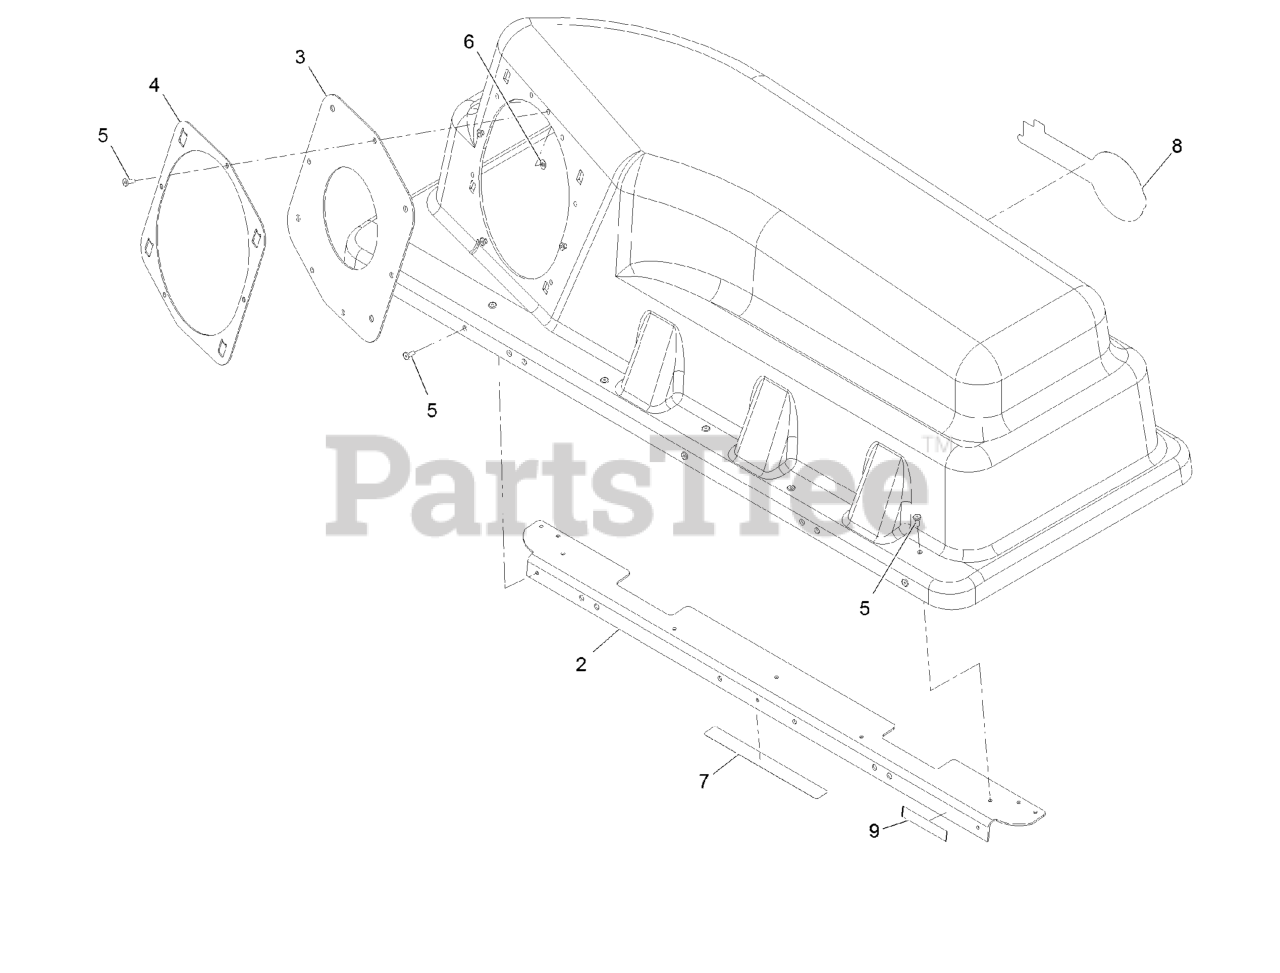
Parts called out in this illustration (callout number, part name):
2	STIFFENER-BAGGER, TOP
4	RING-RETAINER
5	RIVET-BLIND
6	WASHER-FLAT
7	DECAL-CRUSH HAZARD BAGGER
8	DECAL-EXMARK LOGO
9	DECAL-WARNING
